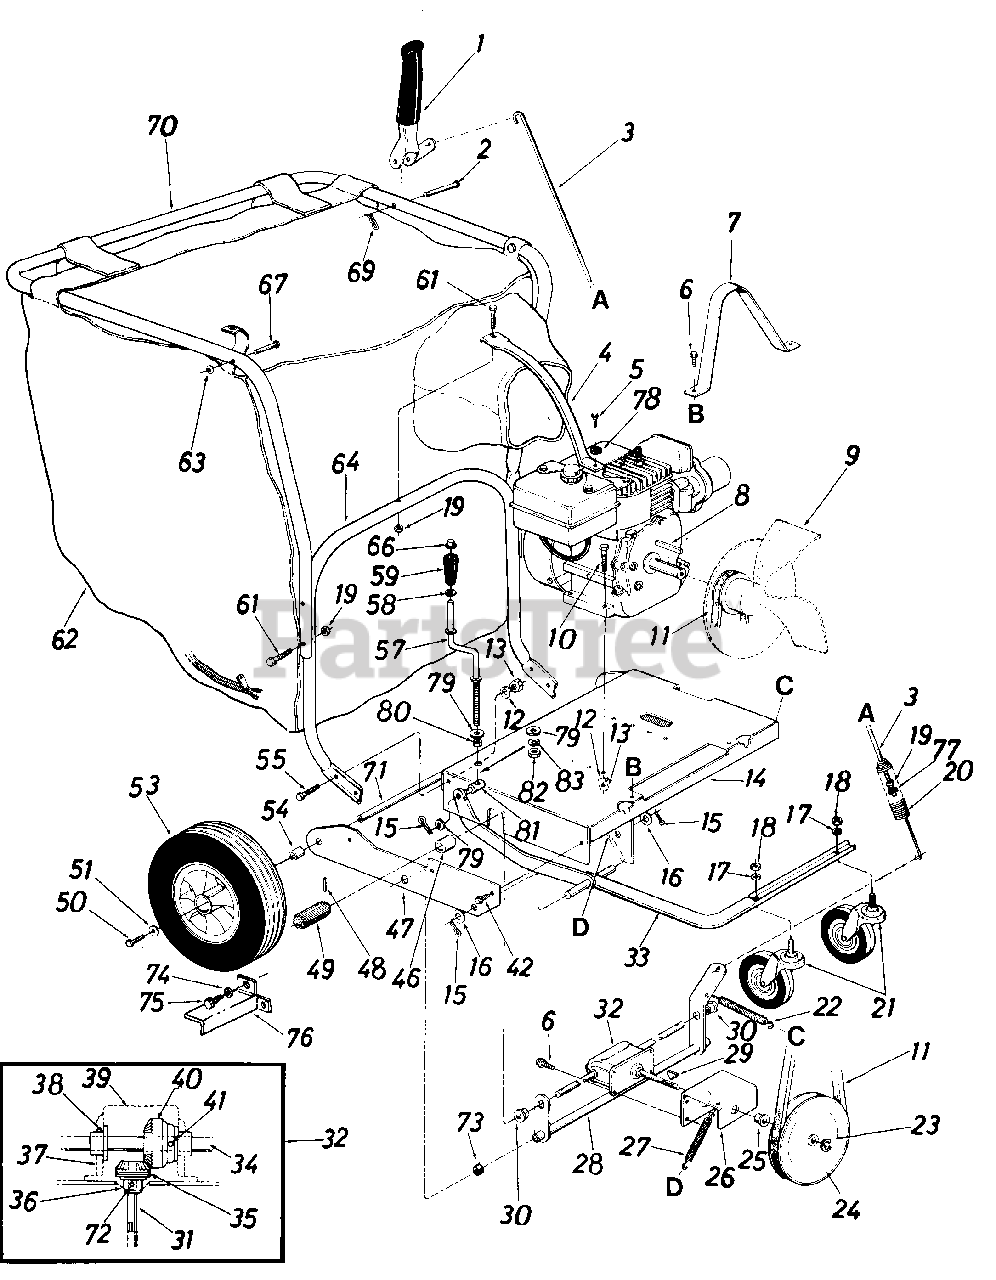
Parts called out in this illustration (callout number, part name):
1	Clutch Grip Ass'y.
2	Clevis Pin .375" Dia. x 1.88"
3	Clutch Rod 32" Lg.
4	Handle Brace
5	Part of Engine
6	Hex L-Wash. Hd. AB Tap Scr. 1/4" x .62" Lg.
9	Air Vane Plate Ass'y. (675 and 677)
10	Hex Bolt 5/16-18 x 1.5" Lg.
11	"V"-Belt 1/2" x 26" Lg.
12	L.-Wash. 5/16" I.D.
13	Hex Nut 5/16-18 Thd.
16	Fl.-Wash. .63" I.D. x 1.25" O.D.
17	L.-Wash. 1/2" I.D.
18	Hex Nut 1/2-13 Thd.
19	Hex Cent. L.-Nut 1/4-20 Thd.
20	Extension Spring .78" O.D. x .75" Lg.
21	Swivel Caster Wheel 5" Dia. x 1.25"
22	Extension Spring .38" O.D. x 7.50" Lg.
23	Snap "E"-Ring.50" Dia. Shaft
24	"V"-Pulley 5/8" x 6.50" O.D.
25	Flange Bearing .502" I.D.
28	Clutch Bracket Ass'y.
29	#2 Woodruff Key 3/32" Dia. x .8 1 " Lg.
30	Hex Flange Bearing Bronze .625" I.D.
31	Pinion Shaft .50" Dia. x 5.0"
32	Gear Box Ass'y. Comp.
35	Bevel Gear .50" I.D. x 14 Teeth
36	Flange Bearing .503" I.D.
37	Gear Box
38	Flange Bearing .630" I.D.
39	Gear Box Cover
40	Bevel Gear .62" 1 .D. x 28 Teeth
41	Spring Pin Spiral 3/16" Dia. x 1.25" Lg.
42	Hex Wash. Hd. "AB" Tap Scr. 5/16" x .75" Lg.
46	Spacer .63 I.D. x .88" O.D. x .56" Lg.
49	Drive Pinion
50	Hex Locking Bolt 5/16-24 x.62" Lg.
51	Fl.-Wash. .34" I.D. x 87" O.D.
53	Wheel Ass'y.-Comp. 12" x 3"
54	Spacer .63" I.D. x 1.00" O.D. x.94" Lg.
55	Hex Bolt 5/16-18 x .75" Lg.
57	Height Adjustment Crank
58	Fl.-Wash. 138" I.D. x .62" O.D.
59	Crank Knob
61	Hex Bolt 1/4-20 x 1.75" Lg.
62	Vacuum Bag-Felt
63	Push Speed Nut .25" Dia. Stud
64	Lower Handle
66	Push Nut 3/8" Dia.
67	Stud Pin .250" Dia. x 1.75"
69	Internal Cotter Pin 3/8" Dia.
70	Upper Handle
71	Rear Axle .624" Dia. x 24.37"
72	Spring Roll Pin 5/32" Dia. x 1.12
73	Spacer .82" I.D. x 1.00" O.D. x .305 Lg.
74	L.-Wash. .265" I.D.
75	Hex Self Tap Scr. 1/4" x 3/8" Lg.
78	Belleville Washer
79	Fl.-Wash. .35 " I.D. x .87 " O.D.
80	Spacer .38" I.D. x .50" O.D. x .180" Lg.
81	Ferrule3/8-16x .38" Dia.
82	Hex Nut 3/8-16 Thd.
83	L.-Wash. 3/8" I.D.
